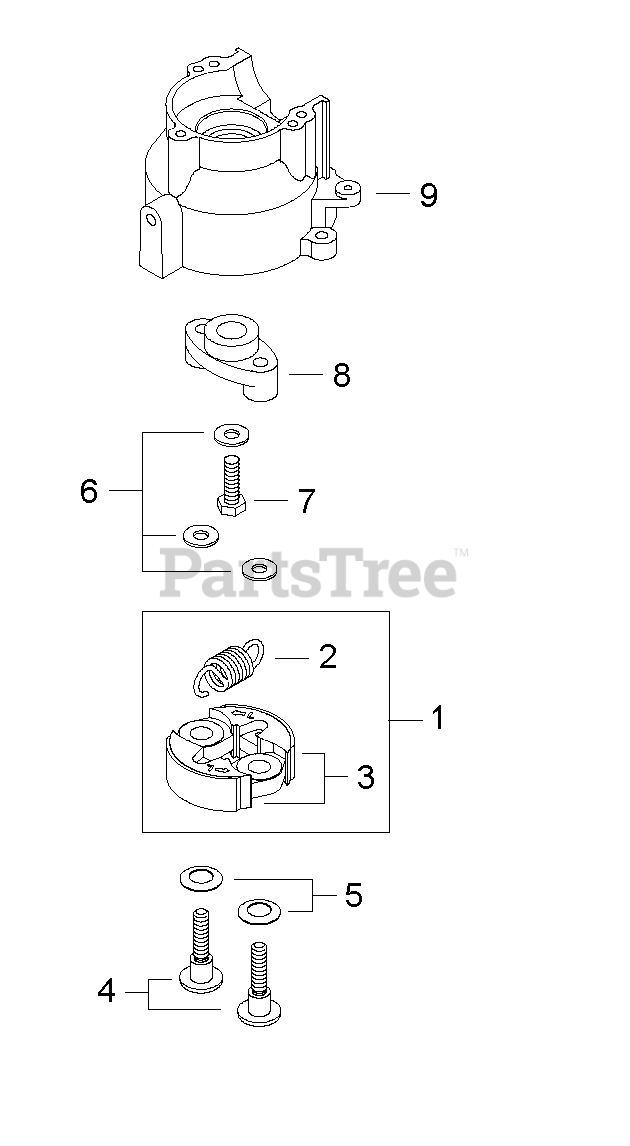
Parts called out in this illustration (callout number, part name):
1	SHOE ASSY, CLUTCH
2	SPRING, CLUTCH
3	SHOE, CLUTCH
4	BOLT, CLUTCH
5	WASHER, SPRING
6	WASHER 6 MM
7	BOLT M6×18
8	BOSS, CLUTCH
9	CRANKCASE ASSY, PTO
